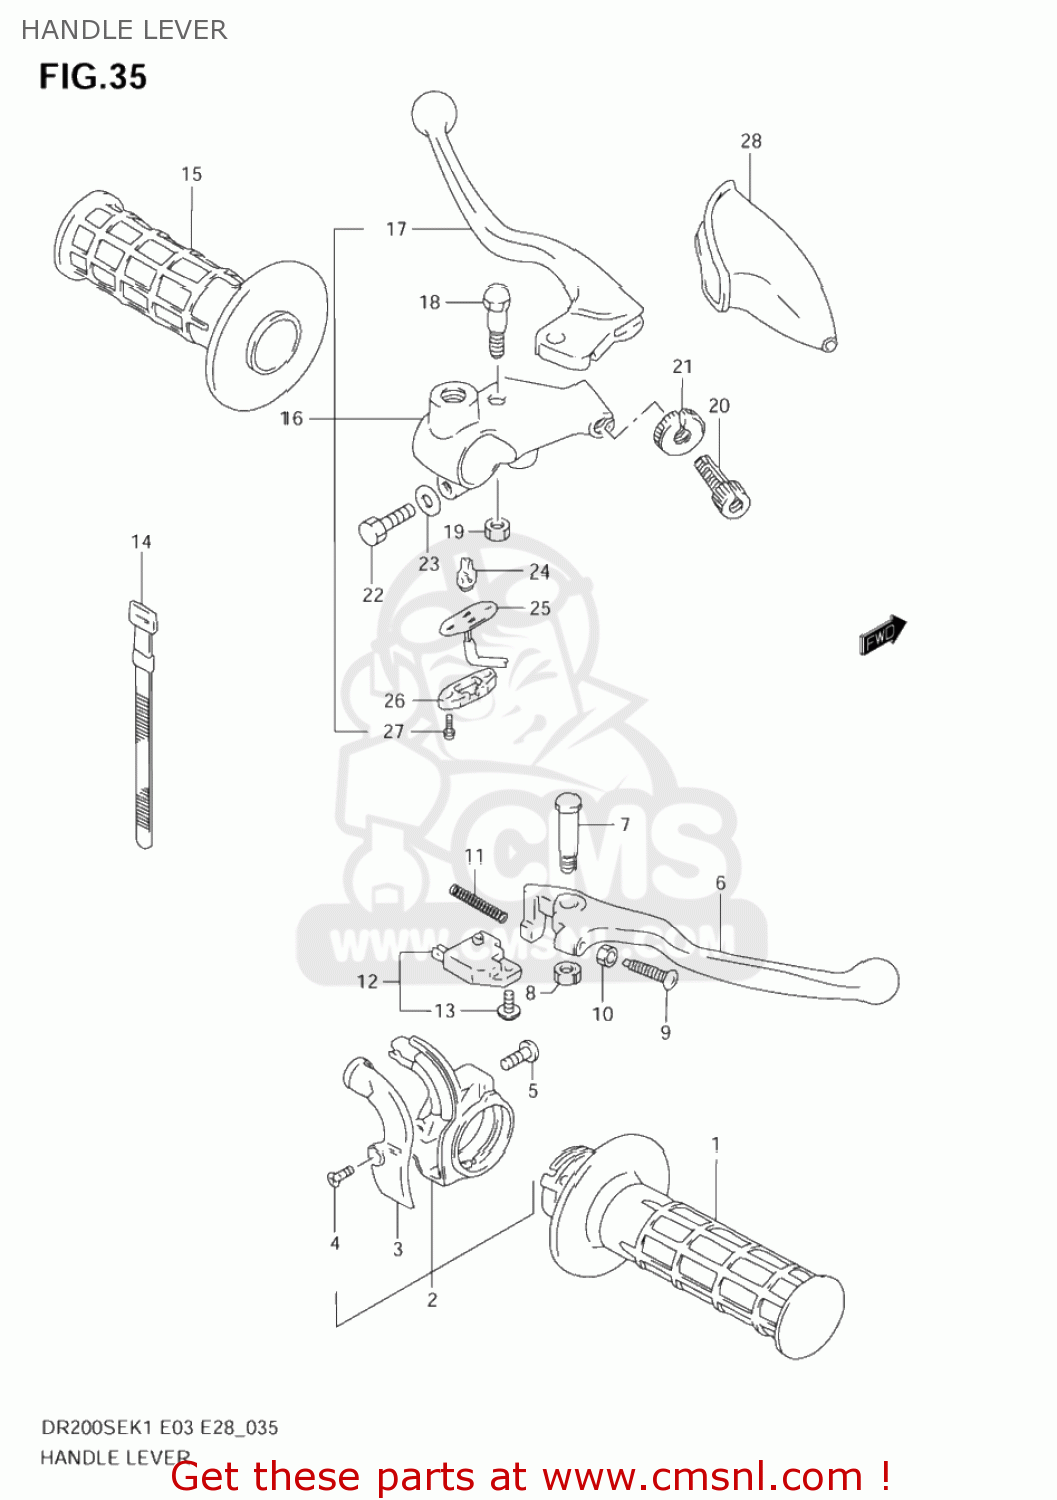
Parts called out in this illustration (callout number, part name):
1	GRIP,THROTTLE
2	CASE ASSEMBLY,THROTTLE
3	COVER,THROTTLE CASE
4	SCREW,UPPER
5	SCREW
6	LEVER,BRAKE
7	BOLT,BRAKE LEVER
8	NUT 6MM
9	BOLT,ADJUST
10	NUT
11	SPRING,RETURN
12	SWITCH ASSY,ST
13	SCREW
14	CLAMP(L:120)
15	GRIP,L
16	LEVER ASSEMBLY,CLUTCH
17	LEVER,CLUTCH
18	BOLT,LEVER PIVOT
19	NUT 6MM
20	ADJUSTER,CABLE
21	NUT,LOCK
22	BOLT
23	WASHER
24	CONTACT,SWITCH
25	HARNESS ASSY,WIRE
26	COVER,FR BK TERMINAL BASE
27	SCREW
28	COVER,CLUTCH LEVER
